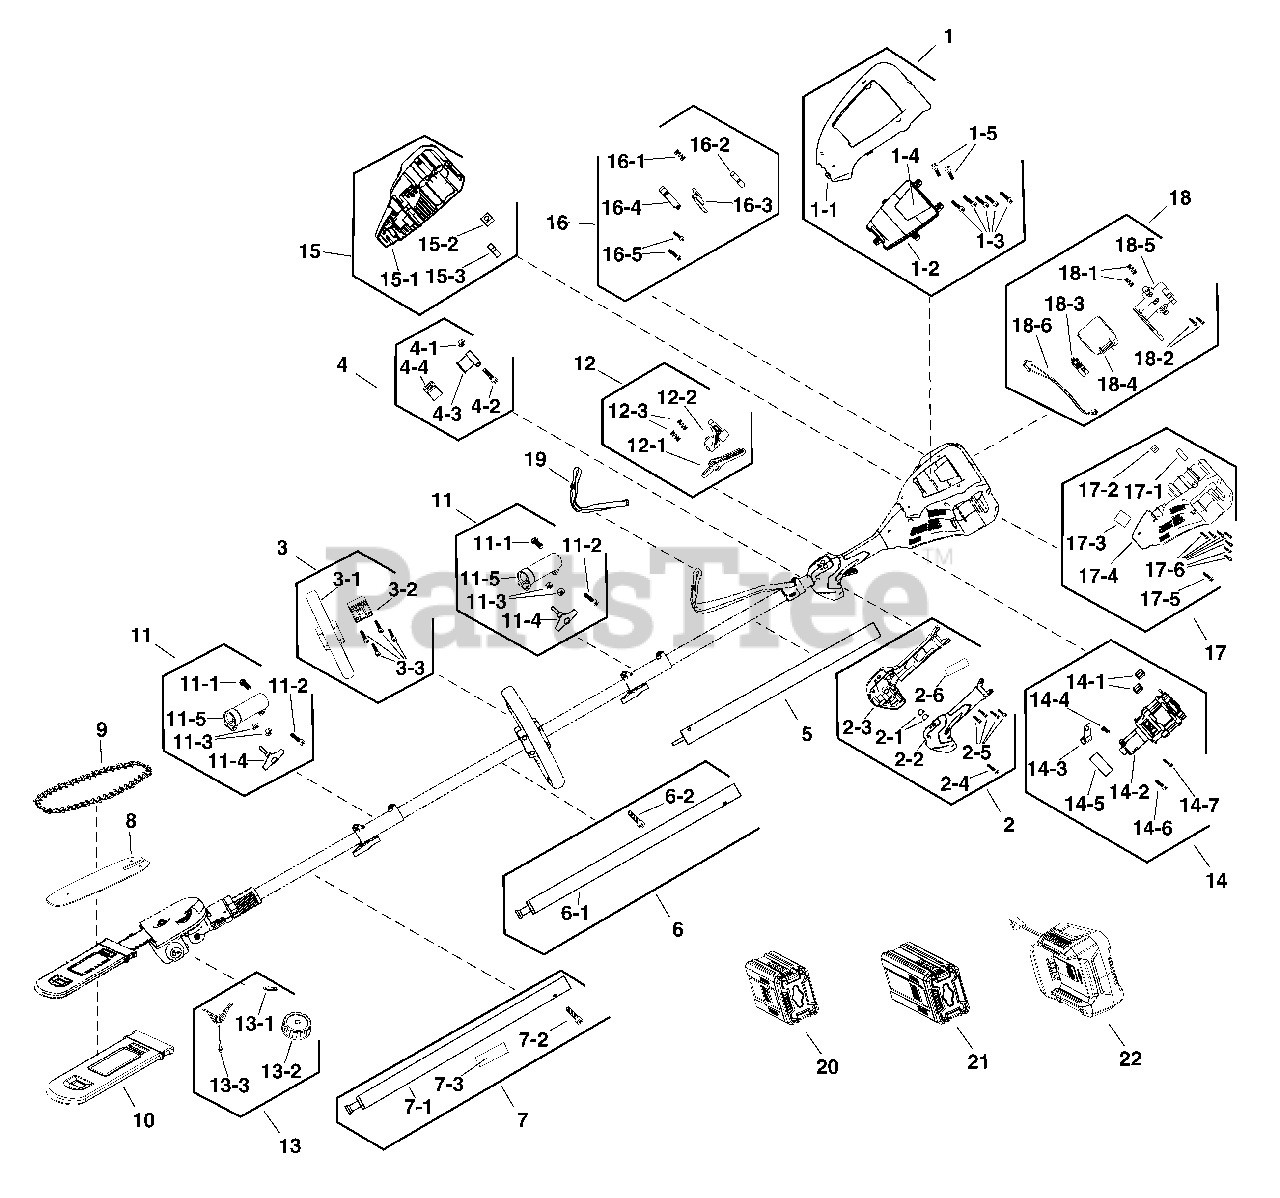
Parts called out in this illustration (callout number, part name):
1	KIT, TOP COVER, NA
1-1	TOP COVER
1-2	TOP COVER INSERT
1-4	LABEL
2	KIT, HANDLE, NA & EU
2-1	BUTTON, PCB
2-2	HOUSING, LEFT HANDLE
2-3	HOUSING, RIGHT HANDLE
2-6	LABEL
3	KIT, AUXILARY HANDLE
3-1	AUX HANDLE
3-2	AUX HANDLE BASE
4	KIT, HARNESS CLAMP
4-1	NUT
4-3	CLAMP, HARNESS
4-4	CLIP, HARNESS
5	KIT, Shaft
6	KIT, MIDDLE SHAFT
6-1	MIDDLE SHAFT
7	KIT, BOTTOM SHAFT
7-1	BOTTOM SHAFT
7-3	LABEL
8	KIT, BAR
9	KIT, CHAIN
10	KIT, COVER
11	KIT, COUPLING
11-3	BOLT
11-4	HANDLE, RELEASE
11-5	COUPLING
12	KIT, SWITCH AND LOCK-OUT BUTTON
12-1	TRIGGER
12-2	BUTTON, LOCK-OUT
12-3	SPRING
13	KIT, OIL CAP
13-1	SEAL RING
13-2	OIL CAP
13-3	OIL CAP CORD
14	KIT, MOTOR
14-1	RUBBER PLAT
14-2	MOTOR
14-3	CLIP
14-5	RUBBER PLAT
15	KIT, RIGHT HOUSING
15-1	MOTOR HOUSING
15-2	BOLT
15-3	RUBBER PLAT
16	KIT, BATTERY RELEASE BUTTON
16-1	SPRING
16-2	PIN
16-3	BUTTON, Battery Releasee
16-4	PRESS PLAT
17	KIT, LEFT HOUSING, NA
17-1	BOLT
17-2	RUBBER PLAT
17-3	LABEL
17-4	MOTOR HOUSING
18	KIT, PCB, NA
18-1	SPRING
18-3	SWITCH
18-4	PCB
18-5	INSERT PLAT
18-6	WIRE HARNESS
19	KIT. HARNESS
20	* BATTERY, 2.0, 82V NA
21	* BATTERY, 4.0, 82V NA
22	* CHARGER, Battery, NA
